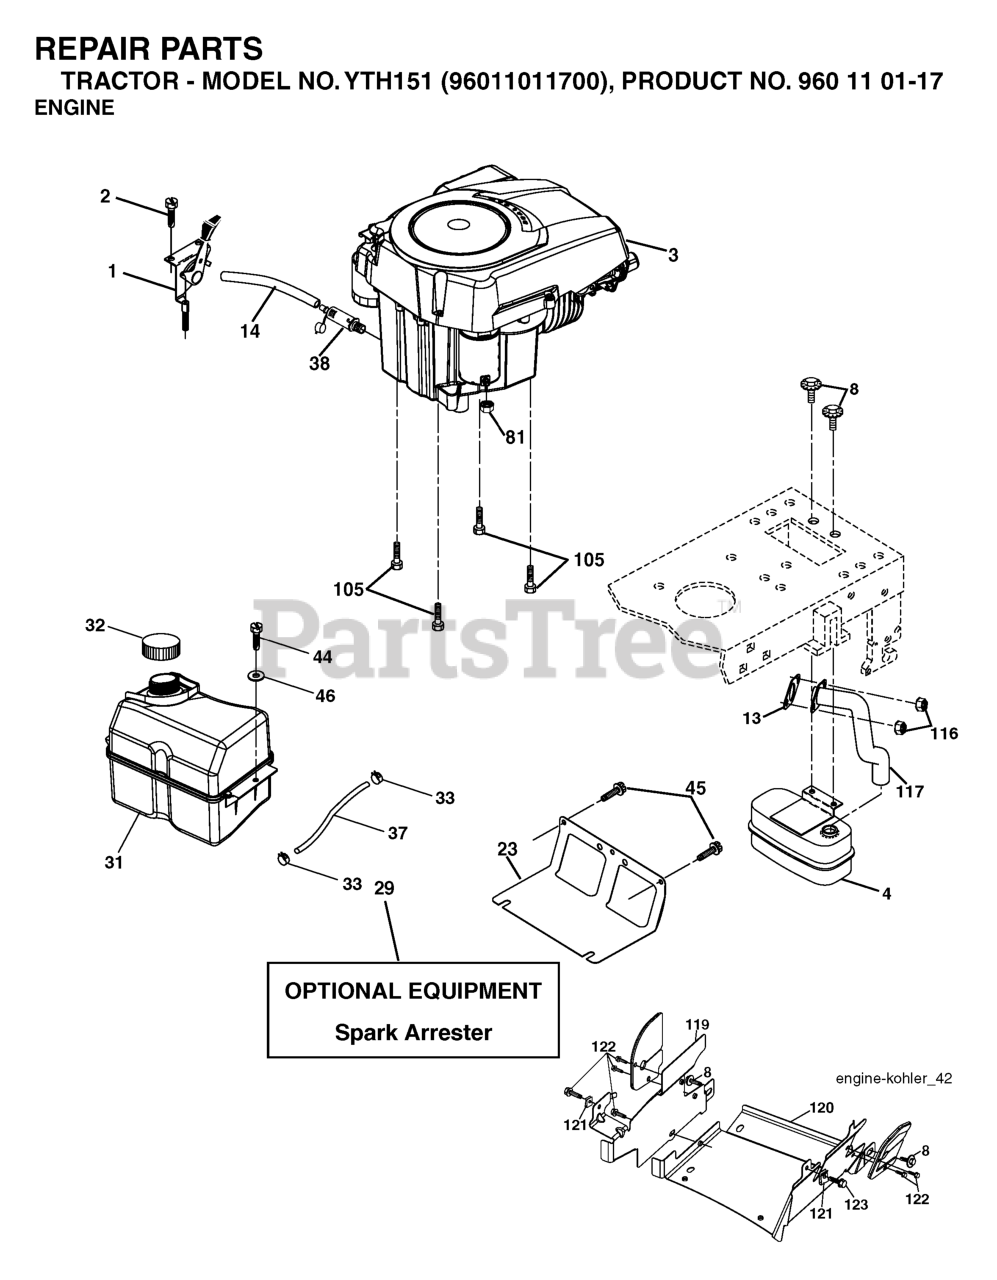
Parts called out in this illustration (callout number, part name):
1	CONTROL.THROTTLE.LT/YT
2	SCREW
4	MUFFLER.SINGLE.CYL.KOHL/B&S
8	BOLT.5/16-18UNCX3/4 W/SEMS.BLK
13	GASKET.EXHAUST.KOHLER
14	TUBE, DRAIN OIL ASM.
23	SHIELD.BROWNING.DBR.GUARD
29	KIT.SPARK ARRESTOR 794945 B&S
31	TANK FUEL
32	FUEL CAP
33	HOSE CLAMP
37	LINE.FUEL.20
38	PLUG DRAIN OIL EASY
44	SCREW HEXWSHR 1/4-20X3/4
45	SCREW, 3/8-16X3/4
81	NUT
105	SCREW 3/8-16X1
116	NUT.HEX.FLANGE.TOPLOCK
117	RP.TUBE.EXHAUST.KOHL.COURAGE
122	SCREW.1/4-20X5/8
123	SCREW, 5/16-18 X 1/2
